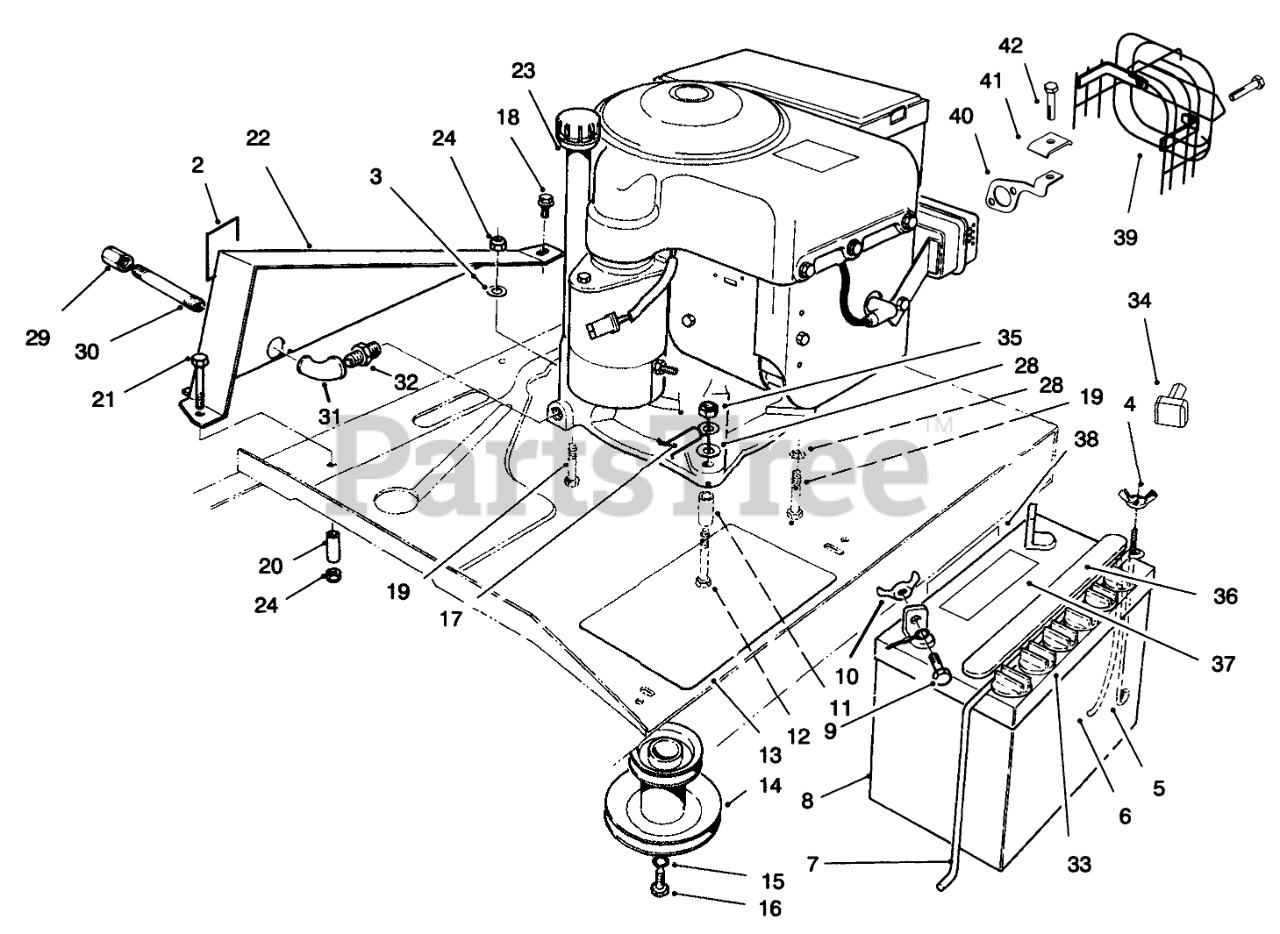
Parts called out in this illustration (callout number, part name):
2	DECAL-EUROPE
3	WASHER-PLAIN
4	NUT-WING
5	POST-BATTERY
6	TUBE-BATT DRAIN/80-2600
7	HOLDDOWN-BATTERY
8	Battery
9	SCREW-HH
10	NUT-WING
11	SPACER-PIVOT
12	SCREW-HH
13	PAD-SKID, ANTI
14	Pulley-Engine
15	WASHER-FLAT
16	SCREW-HH
17	WIRE ASM
18	SCREW-HWHTF
19	SCREW-HH
20	GUIDE-BELT
21	SCREW-HH
22	GUIDE-CHAIN
23	Engine-8 H.P. B & S
24	NUT-LOCK, NI
28	WASHER-LOCK
29	CAP-PIPE
30	NIPPLE-PIPE
31	ELBOW-STREET
32	BUSHING-PIPE
33	CAP-BATTERY
34	BOOT-TERMINAL
35	NUT-HEX, SIDE DEFORM
36	DECAL - DANGER
37	DECAL-DANGER
38	DECAL-BATTERY
39	GUARD - MUFFLER
40	BRACKET - MUFFLER GUARD
41	TAB - MUFFLER GUARD
42	SCREW-HWHTF
